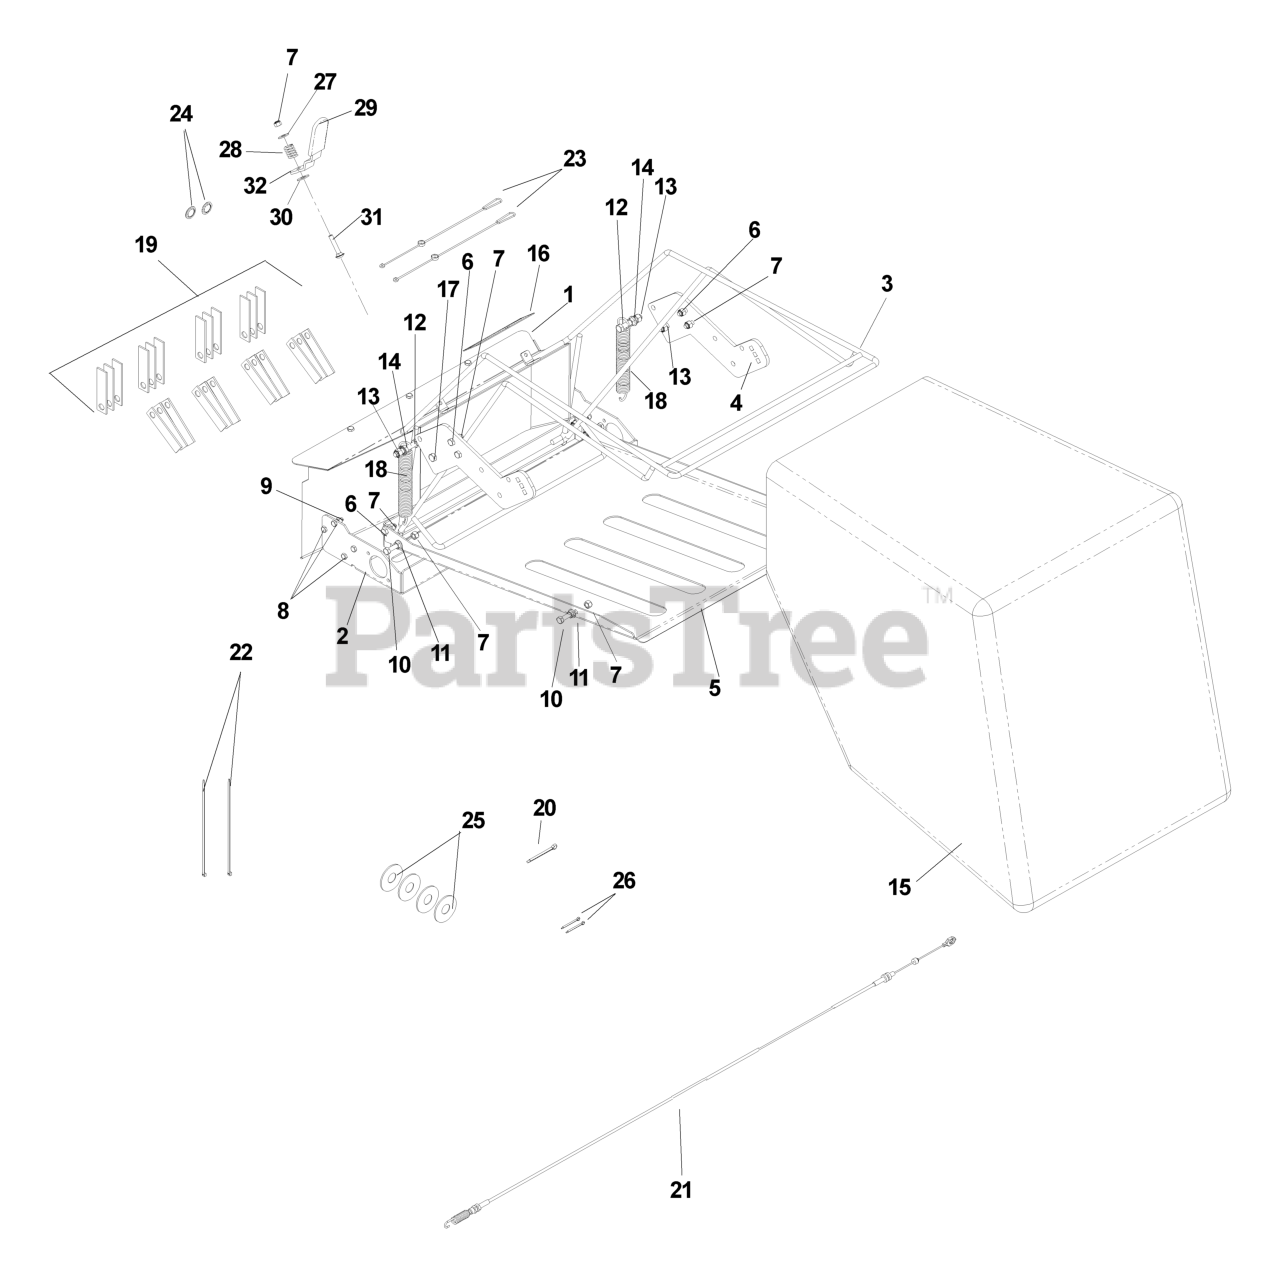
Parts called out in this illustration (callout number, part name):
1	CHUTE
2	BAGGER TRAY
3	BAG FRAME, BLACK
4	EXTENDER GREY
5	SAFETY DOOR ORANGE
6	HCS 5/16C X 1
7	NUT 5/16 NYLOC
8	HCS 1/4C X 3/4 HCS
9	NUT.1/4-20.HEX.NYLOC.ZD
10	HCS 5/16C X 1 3/4
11	NUT 5/16C WHIZ
12	HCS 3/8C X 2
13	NUT 3/8-16 NYLOC
14	NUT 3/8C WHIZ
15	CATCHER BAG
16	DECAL, WARNING
17	HCS 3/8-16X1.GRD.5.ZD
18	SPRING BAGGER
19	BLADE SET, 56 BLADES
20	COTTER PIN
21	CABLE 46.5" POWER RAKE
22	TIE, PLASTIC
23	LANYARD
24	RETAINING RING
25	WASHER
26	COTTER PIN
27	WASHER 5/16 FLAT
28	COMPRESSION SPRING
30	WASHER 3/8 FLAT
31	RHSNB 5/16-18X1 3/4
